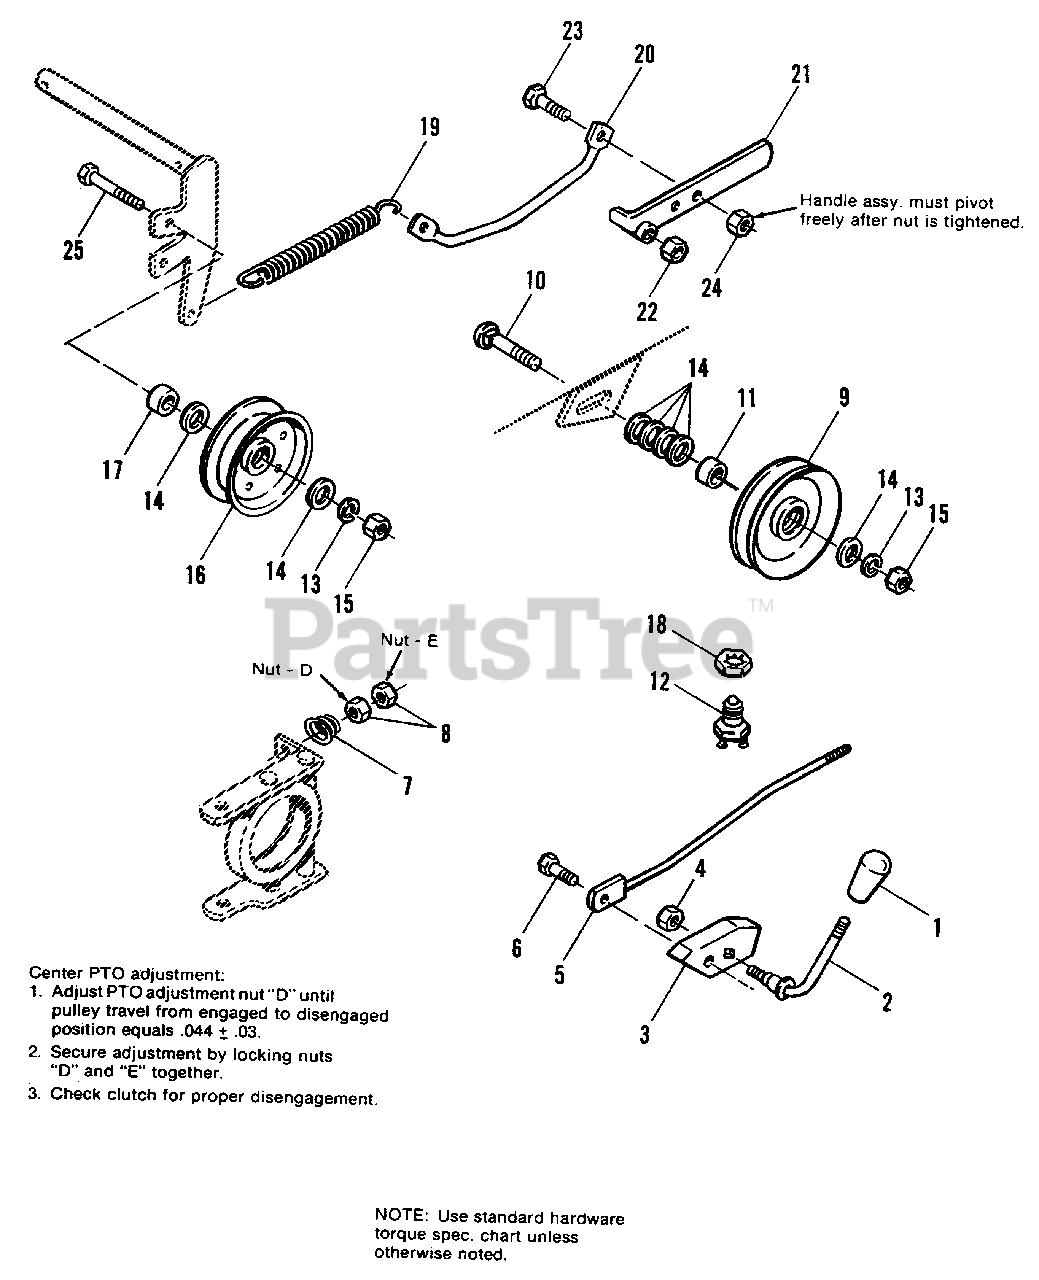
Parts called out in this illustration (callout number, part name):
1	KNOB
2	HANDLE, Clutch P.T.O.
4	LOCKNUT, Hex, 3/8-16
5	CONTROL ROD ASSY.
6	CAPSCREW, Special
8	NUT, Hex, Full, 5/16-18
9	PULLEY ASSY., W/Bearing
10	BOLT, Carriage, 3/8-16 x 1-1/2
12	SWITCH, Interlock
13	LOCKWASHER, 3/8
14	WASHER, 5/16
15	NUT, Hex, Full, 3/8-16
16	PULLEY, Idler
18	NUT, Pal
19	SPRING, Tension
20	ROD, Tension
21	HANDLE ASSY.
22	LOCKNUT, Hex, 7/16-14
23	CAPSCREW, Hex Hd., 5/16-18 x 3/4
24	LOCKNUT, Hex, 5/16-18
25	CAPSCREW, Hex Hd., 3/8-16 x 2
